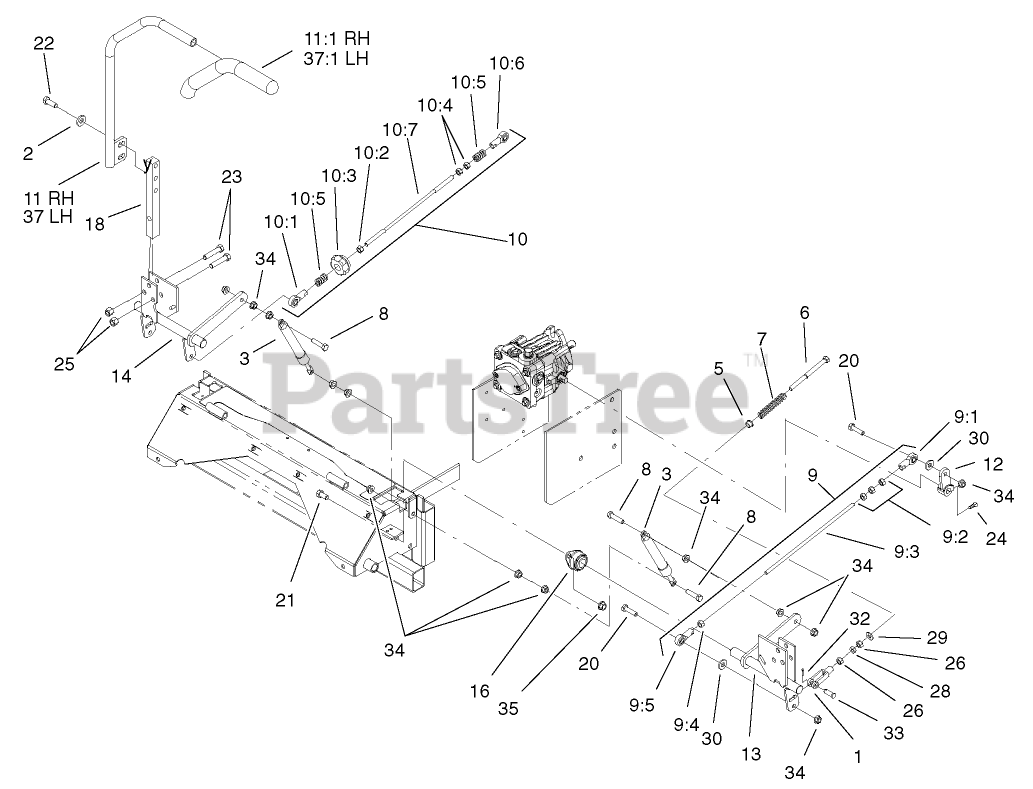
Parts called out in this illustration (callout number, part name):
1	YOKE-ADJUSTABLE
2	WASHER-BELLEVILLE
3	Damper-Control, Motion
5	BUSHING-FLANGED
6	BOLT-RETURN, NEUTRAL
7	SPRING-RETURN, NEUTRAL
8	SCREW-HH
9	Rod/Balljoint ASM
9:1	BALLJOINT-RH
9:2	NUT-HEX
9:3	LINKAGE-PUMP/LEVER
9:5	BALLJOINT-LH
10	Tracking Rod ASM
10:1	BALLJOINT-RH
10:2	NUT-HEX
10:3	KNOB-TRACKING
10:5	SPRING-COMPRESSION
10:6	BALLJOINT-LH
10:7	Link-Rod, Tracking
11	RH LEVER ASM
11:1	GRIP-CONTROL, MOTION
12	ARM-CONTROL, PUMP
13	CONTROL-MOTION, LH
14	CONTROL-MOTION, RH
16	BEARING-FLANGE, SIDE
18	ARM-SHAFT, CONTROL
20	SCREW-HH
21	SCREW-HH
22	SCREW-HH
23	SCREW-HH
24	SCREW-SET
25	NUT-LOCK, NI
26	NUT-HEX
28	NUT-JAM
29	WASHER-FLAT
30	WASHER-FLAT
32	PIN-COTTER
33	PIN-CLEVIS
34	NUT-HF
35	NUT-HHF, WHIZ
37	LH LEVER ASM
37:1	GRIP-CONTROL, MOTION
